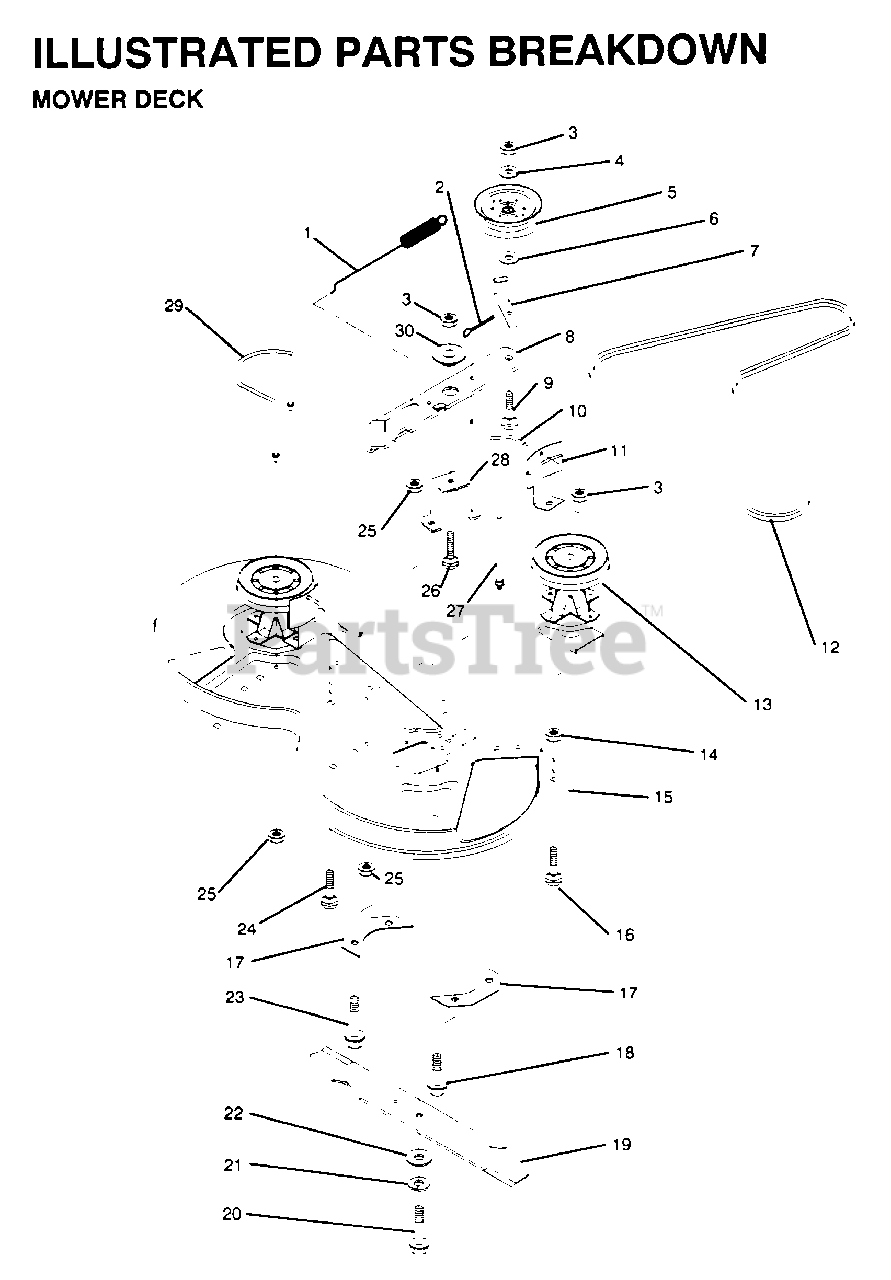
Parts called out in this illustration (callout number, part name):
4	WASHER
6	WASHER GT
8	IDLER ARM ASS'Y
9	BOLT CARRIAGE
10	ROD BRAKE
11	BRAKE LT
12	BELT.MOWER.79.75
13	MANDREL ASS'Y
16	BOLT
17	SUPPORT PLATE LT
18	SCREW
19	"BLADE.36""HIGH LIF"
20	BOLT.3/8-24X1-1/2
22	WASHER
23	SCREW
24	BOLT
26	BOLT D
27	"GUIDE,REAR BEL RH"
28	"SUPT,IDLER ARM"
29	GUIDE BELT LH
30	SPACER RETAINER
